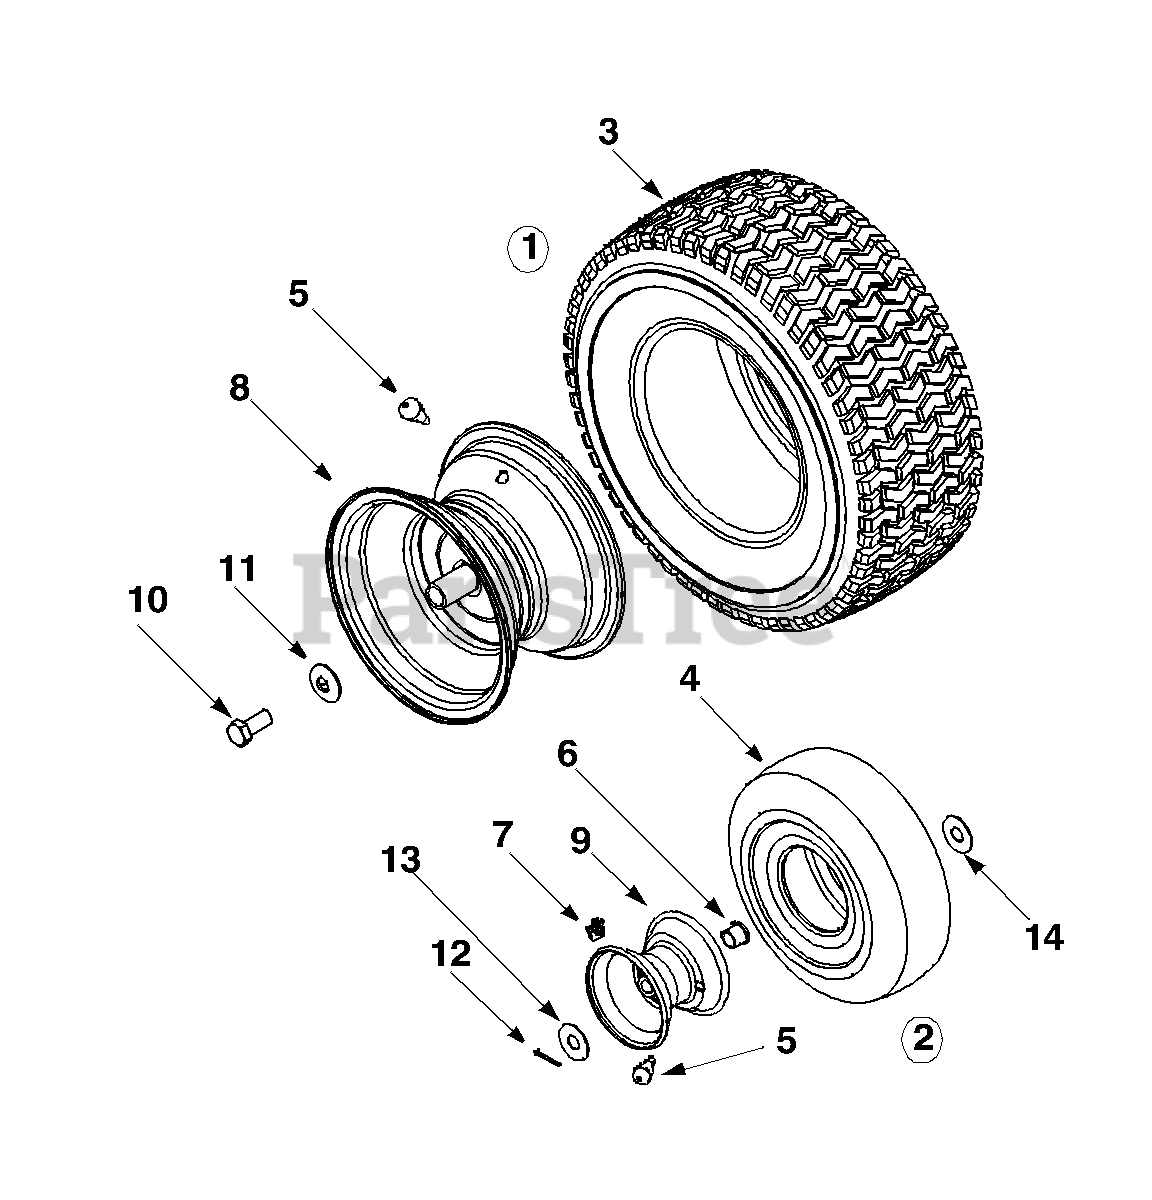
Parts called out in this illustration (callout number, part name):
5	Valve: Tubeless Air
6	Grease Fitting
7	Flange Bearing
11	Beleville Washer
